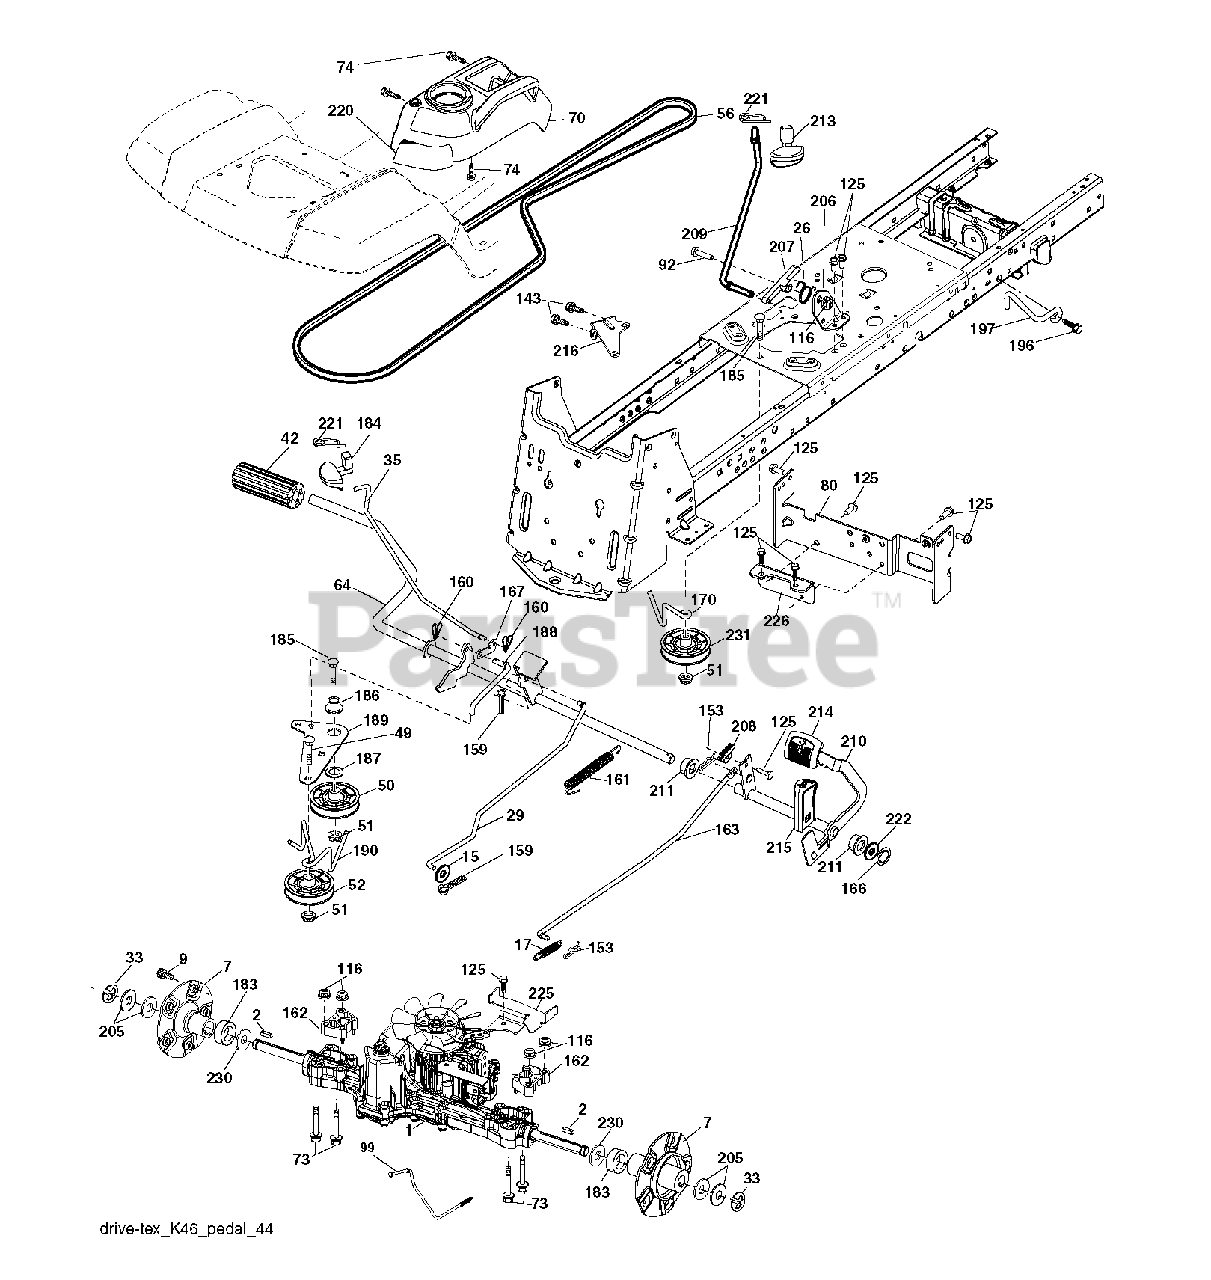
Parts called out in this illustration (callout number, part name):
2	KEY.SQUARE.187X2.500
7	HUB.ASM.WHEEL.REAR.22"
15	WASHER
17	SPRING.BRAKE.K46.GREEN
26	SPRING.RETURN.CRUISE
29	ROD.BRAKE.K46
35	ROD.BRAKE.PARTK.HUSQ.TEX
42	PEDAL COVER T
50	IDLER.FLAT.910.OFFSET
51	NUT LOCK FLG 3/8-16 UNC
52	IDLER.V-GROOVE.910.OFFSET
56	V-BELT.MOWER.92.40.42/K46
64	SHAFT.ASM.PEDAL.BRK.CNTR
70	CONSOLE.ASM.RH.GT.FC.HUSQ
73	BOLT.HEX.FLNG.5/16-18X3.75
74	SCREW.HI-LO.CONSOLE
80	STRAP.TORQUE.K46.K57R.TT
92	BOLT
99	ROD.SPRING.BYPASS.K46.TEX.GT
116	NUT LOCK HEX FLANGE 5/16-18
125	SCREW
143	SCREW LT
153	RETAINER M
159	COTTER PIN
160	RETAINER CLIP
161	SPRING, RETURN LT
162	SPACER.TRANSAXLE.18&22
163	ROD.CONTROL.PEDAL.K46
166	NUT.PUSH.625
167	LATCH.BRAKE.SPRING
170	KEEPER.CENTER SPAN.1.688
183	SPACER.SPLIT.800X.350
184	RB HANDLE.PARKG.BRK.HUS/PRED
186	SPACER.RETAINER
187	WASHER 12/32X2X10GA
188	RP LINK.CLUTCH.GROUND.DRIVE
189	BELLCRANK.GROUND.DRIVE.TEX.
190	KEEPER.BELLCRANK.DRIVE
196	SCREW 3/8-16X1
197	BRKT.ANIT-ROTATION.CLUTCH
206	BRKT.MOUNT.LATCH.CRUIS
207	LATCH.CONTROL.CRUISE
208	GEAR.SECTOR.CONTROL.CR
209	ROD.CONTROL.CRUISE.GT.
210	ROCKER.ASM.PEDAL.CONTR
211	BEARING.NYLON
213	KNOB.CONTROL.CRUSIE.HU
214	PEDAL.FORWARD.PAD.TEX
215	PEDAL.REVERSE.TEX.GT.4
216	BRACKET.PULLEY.IDLER.W/TEX
220	REFLECTOR.RH.TEX GT
221	RETAINER.SPRING.CLIP.H
222	WASHER 21/32 X 1-1/4 X 10 GA.
225	KEEPER.BELT.TRANSAXLE.K46
226	BRKT.MOUNT.TORQUE.K46.
230	WASHER.HARDENED
231	IDLER.V-GROOVE.1.688.OFFSET
